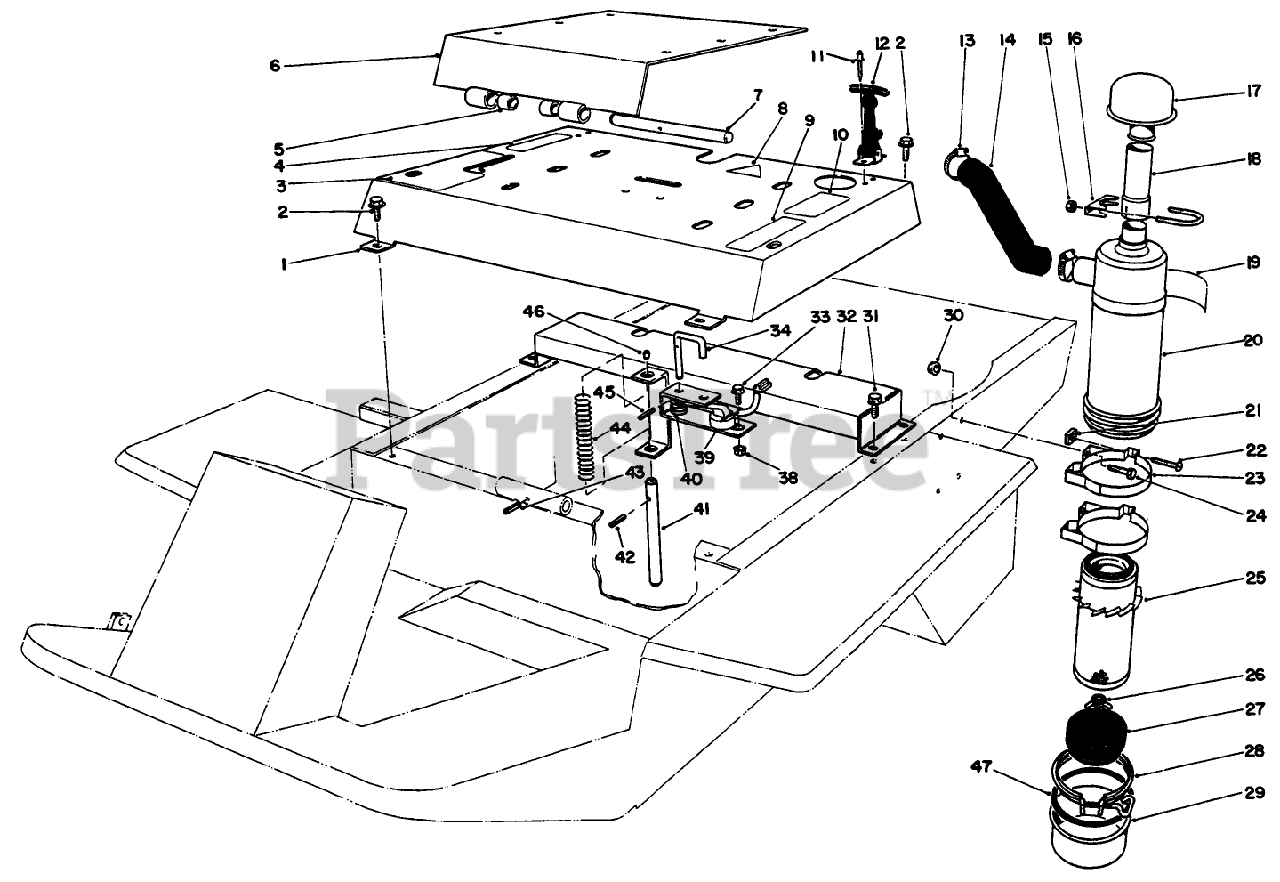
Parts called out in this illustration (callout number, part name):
1	Cover-Seat Support (Incl. Ref. #4, 5, 9 & 10)
2	SCREW-HHFTF
3	DECAL - LIFT CONTROL
4	DECAL-WARNING
5	.503ID X .875LG BSHG
6	Mounting-Seat (Incl. Ref. #5)
7	SHAFT-PIVOT, SEAT
8	DECAL-DANGER
9	DECAL - CAUTION
10	DECAL-REFUELING
11	RIVET
12	Assembly-Handle
13	CLAMP-HOSE
15	NUT-HEX
16	CLAMP-MUFFLER
18	Tube-Air Cleaner
19	DECAL-INSTALLATION
20	Assembly-Air Cleaner (Incl. Ref. #18 & 24-28)
21	NUT-SQUARE
22	SCREW
23	Assembly-Mounting, Band (Incl. Ref. #20 & 21)
24	SCREW-HH
25	ELEMENT ASM
26	NUT AND GASKET ASM
27	SKIRT-BAFFLE
28	CLAMP ASM
29	A/C CUP ASM
30	NUT-HF
31	SCREW-HHF
32	Seat Support
33	SCREW-HHF
34	SEAT SWITCH PIN
35	WASHER-LOCK
38	NUT-HF
39	SWITCH ARM
40	SPRING
41	PIN-SWITCH, SEAT
42	PIN-ROLL, SLOTTED
43	PIN-ROLL, SLOTTED
44	SPRING-COMP
45	PIN-ROLL, SLOT
46	PIN-PEDAL
47	GASKET
